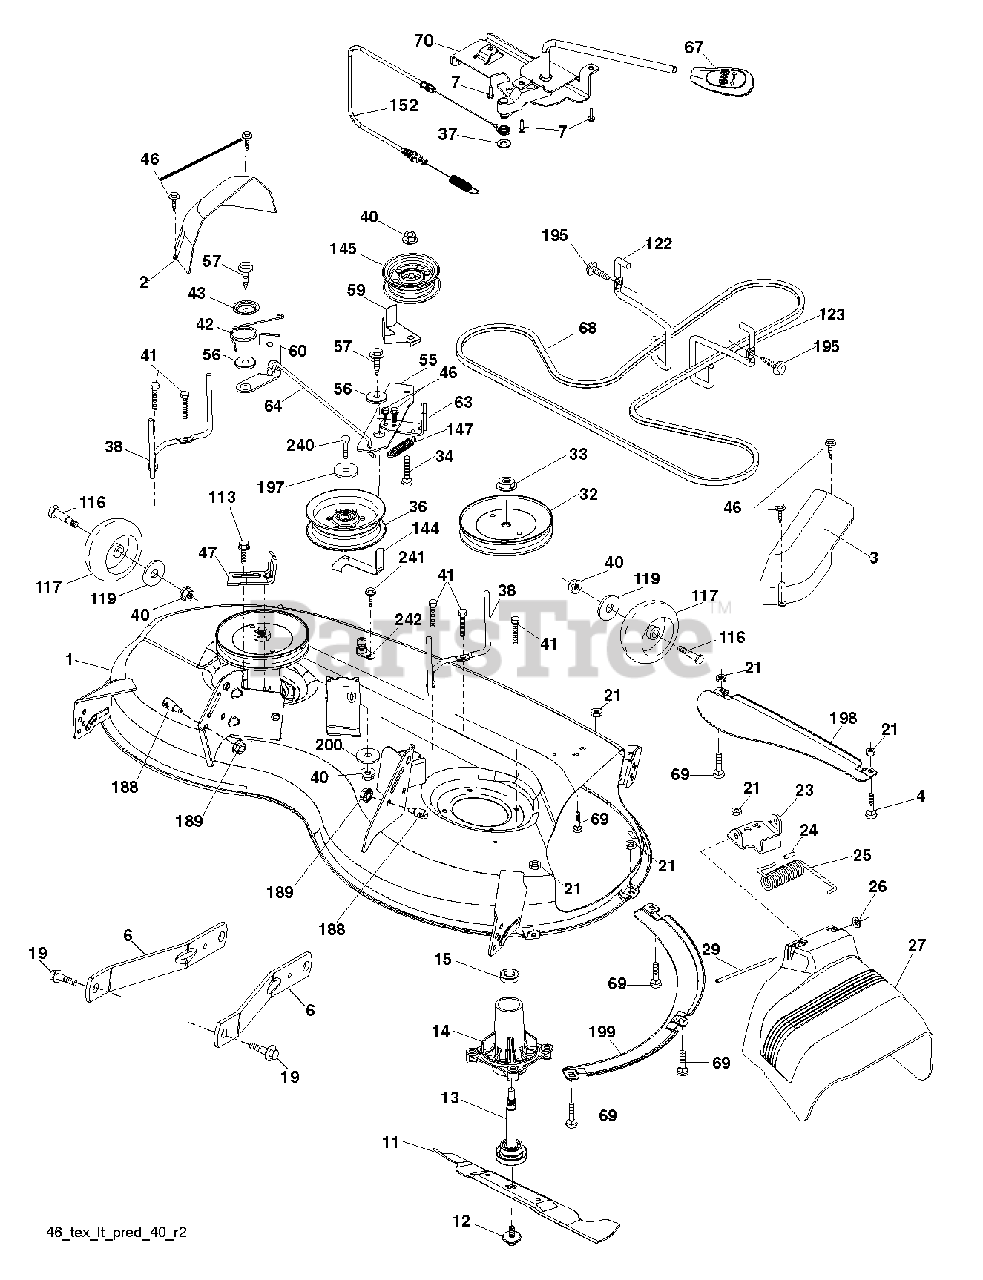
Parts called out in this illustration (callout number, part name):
1	DECK.SVC.46"
2	COVER.MANDREL.RH.46"
3	COVER.MANDREL.LH.46"
4	BOLT
6	ARM.SUSPENSION.MOWER.R
7	SCREW.#10 X 0.750.BOS
11	BLADE.MOWER.46".HI.LIFT
12	SCREW.SEMS.7/16-20X1.HEX.HEAD
13	SHAFT.ASM.MDRL.N/GREASE.38
14	HOUSING.MANDREL.4PT.
19	BOLT.SHOULDER
21	LOCKNUT
23	BRKT.DEFLECTOR.38"2005+
24	CAP-SLEEVE LT
25	SPRING.TORSION.DEFLECT
26	NUT PUSH M
27	SHIELD.DEFLECTOR.MOWER.46"BLAC
29	ROD.HINGE
32	PULLEY.MANDREL.5.438.PD
33	NUT.FLANGE.LOCK.TOP
34	BOLT.3/8-16X1.50
36	PULLEY.IDLER.2006
37	WASHER
38	KEEPER.BELT.MANDREL.PULLEY
40	NUT LOCK FLG 3/8-16 UNC
41	BOLT.HEX.WASHR.HED.313-18X1.19
42	SPRING.TORSION.BRAKE
43	SRPING.TORSION.RETAINE
46	SCREW.1/4-20X5/8
47	BRKT.CLUTCH.CABLE
56	SPACER.RETAINER
57	SCREW 3/8-16X1
59	GUARD, BELT
60	ARM BRAKE MOWER RH 38"
63	ARM BRAKE MOWER
64	LINKAGE BRAKE
67	HANDLE.CLUTCH.CABLE.LT
68	V-BELT
69	BOLT
70	CLUTCH.ASM.MANUAL.YT.PREDATORQ
113	BOLT.5/16HEX.WHS.HD
116	BOLT.SHOULDER.3/8-16X3-5/8.
117	WHEEL. GUAGE RALLY
119	WASHER
122	KEEPER BELT ENGINE LH
123	KEEPER BELT RH
144	KEEPER.BELT.MOWER
145	PULLEY.IDLER.48"PRIMARY
147	SPRING RETURN
152	CABLE.MECHANICAL.CLUTCH
188	STUD.FASTNER.W/ANTI-ROTATE
189	NUT LOCK HEX FLANGE 5/16-18
195	SCREW, 3/8-16X3/4
197	WASHER
198	BAFFLE CENTER FRONT
199	BAFFLE FRONT RH
200	WASHER.13/32 X 1 X 1/2.11GUARD
240	BOLT-HEX EAK
241	SCREW.TT.#10-32X.5.3/8.FLANGE
242	PORT.WASHOUT
